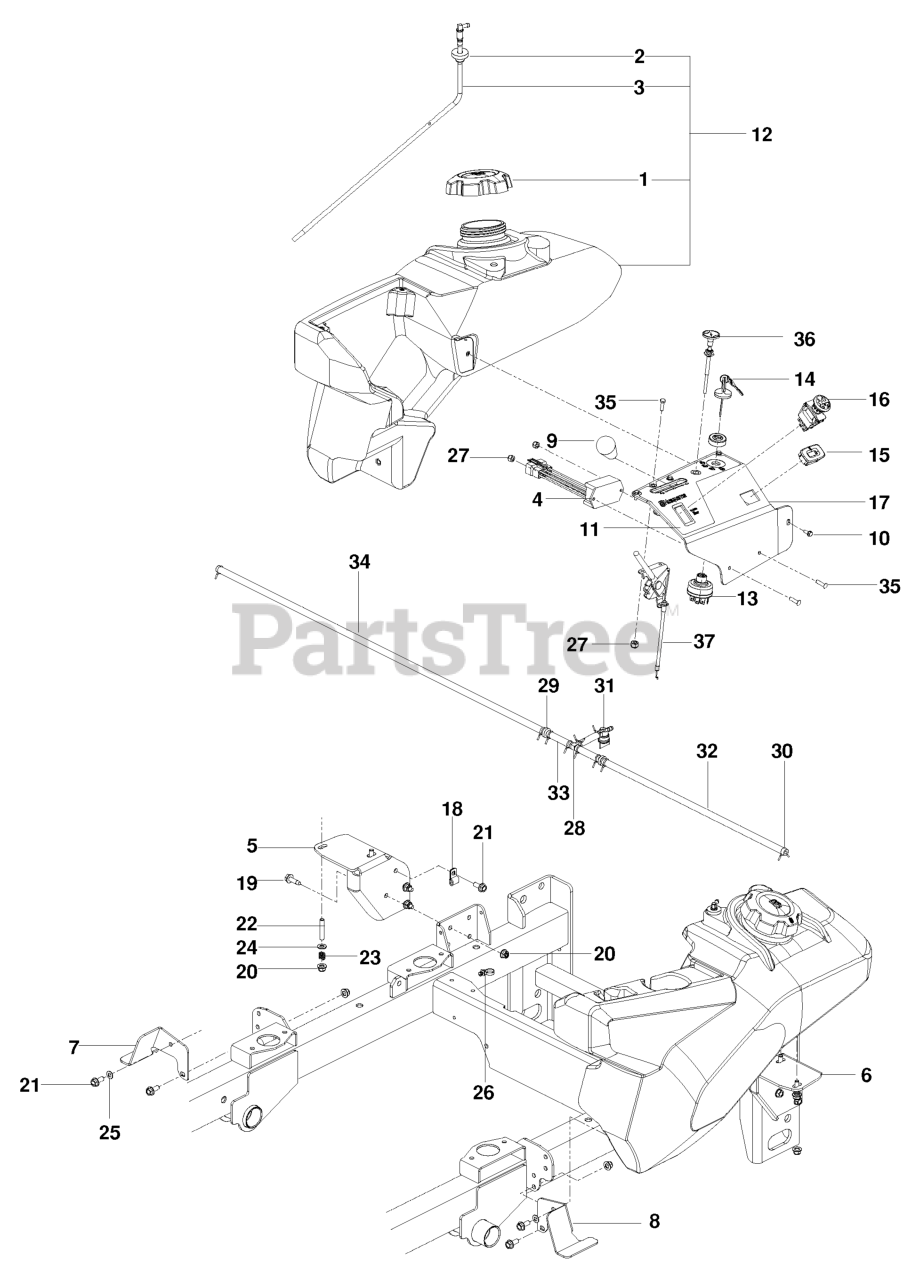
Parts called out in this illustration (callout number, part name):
1	FUEL CAP, HTC
2	RUBBER GROMMET
3	FITTING, FUEL
4	TIMER, SEAT
5	MOUNT, RT TANK, BLK
6	MOUNT, LT TANK, BLK
7	MOUNT, TANK, RT
8	MOUNT, TANK, LT
9	KNOB - SHIFT
10	SCR #10-24 X 3/8 SKT HD BLK OX
11	DECAL, CONTROL, GAS
12	FUEL TANK ASM RT
13	FUEL TANK ASM LT
14	SWITCH, IGNITION, INDAK
15	KEY, IGNITION
16	HOUR METER
17	SWITCH, PTO 10 AMP
18	PANEL.CONTROL.GAS.GRAY
19	DOUBLE TUBE CLAMP
20	RP BLT 5/16-18 X 1 THRD FORM D
21	5/16-18 NYLOC FLANGE NUT
22	HHFS 5/16-18 X 3/4
23	STUD, 5/16C
25	FLAT WASHER 5/16 SAE
26	WASH 5/16 DISC SPRING ZD
27	TIE WRAP, 8-3/8", W/CLIP
28	NUT 10-24 NYLOC
29	TEE, FUEL LINE, .25
30	VALVE, CHECK, .25
31	HOSE CLAMP
32	FUEL VALVE
34	FUEL LINE 3"
36	SCR #10-24 X .75 SKT HD BLK
37	CABLE, THROTTLE, 60"
